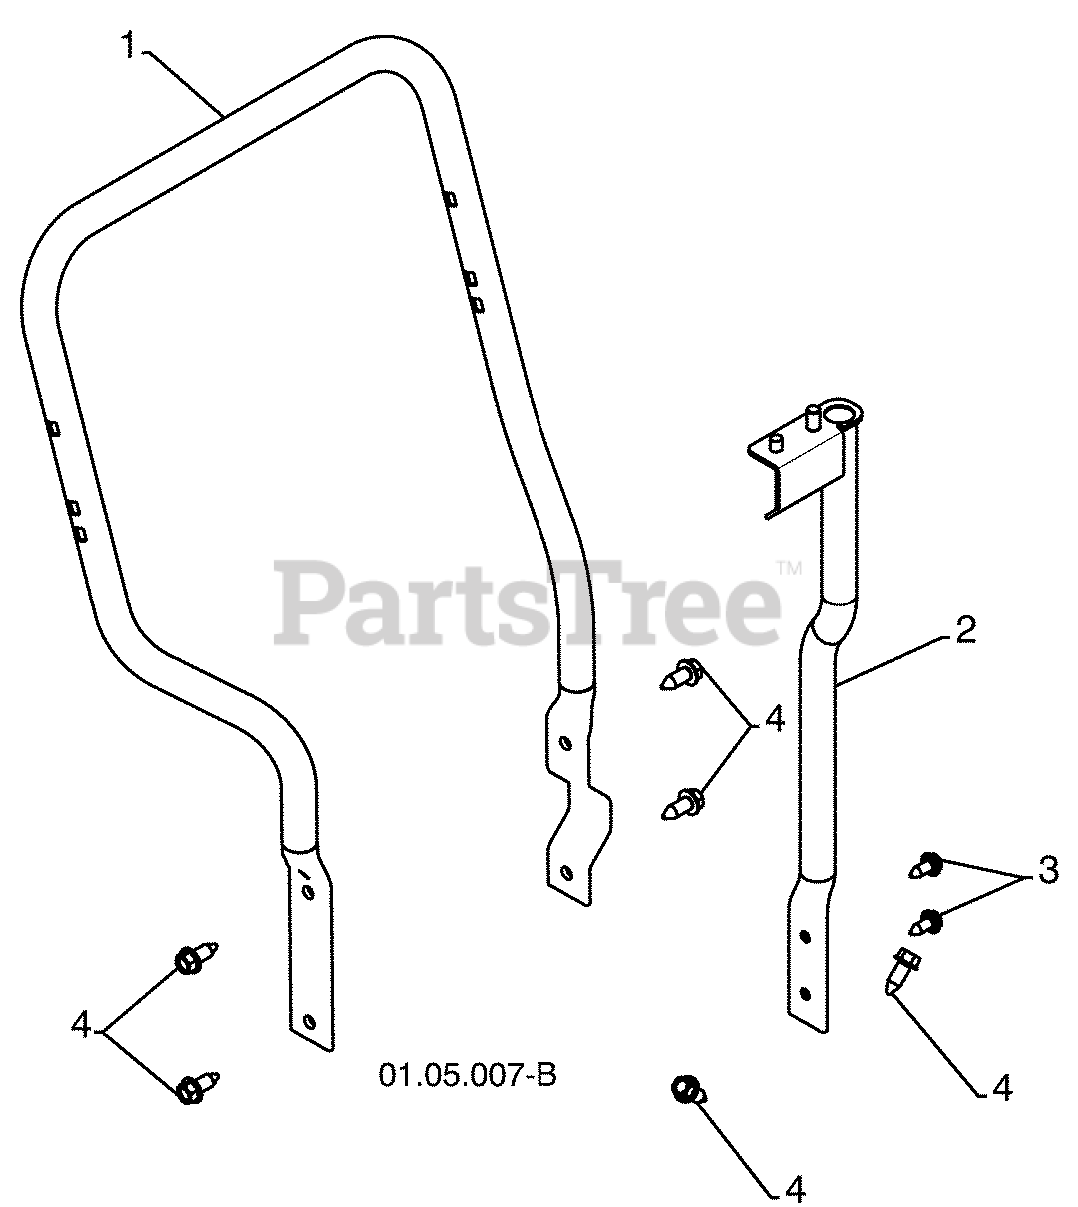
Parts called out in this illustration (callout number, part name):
1	TUBE.LOWER.HANDLE.SNOW.GRAY
2	SUPPORT.WELDMENT.ROTATOR.
3	SCREW
4	SCREW 3/8-16X1
